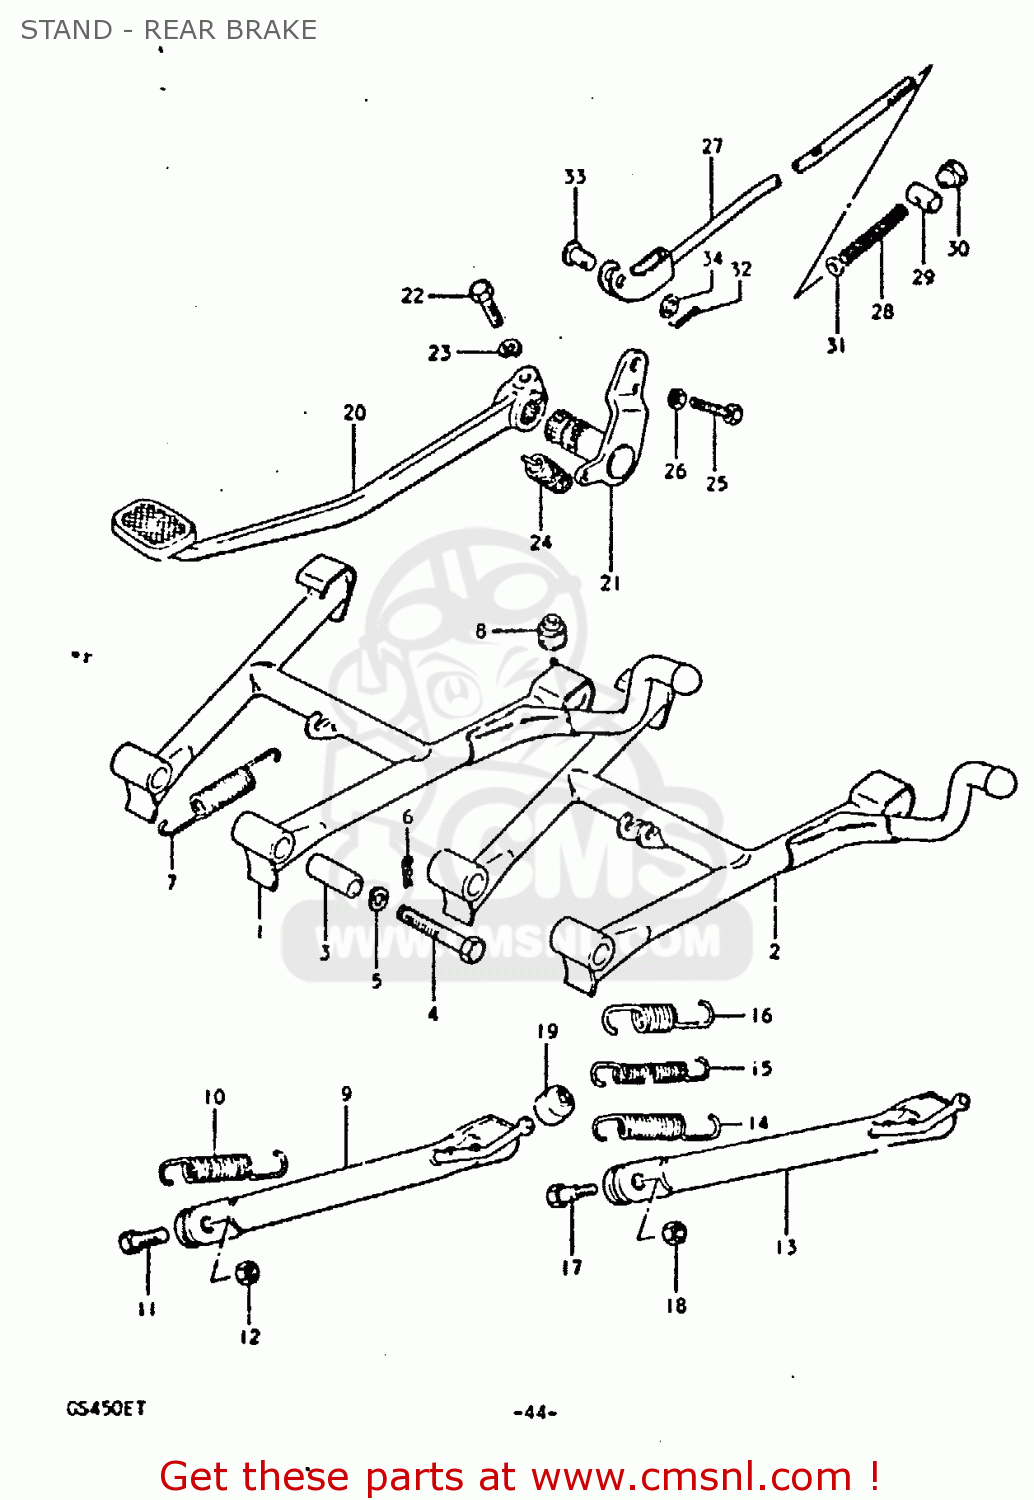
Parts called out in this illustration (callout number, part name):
1	STAND,CENTER
3	SPACER(10X16X38.8)
4	BOLT
5	LOCK WASHER
6	CLIP
7	SPRING
8	CUSHION
9	STAND,SIDE
10	SPRING
11	BOLT(10X30)
12	NUT
19	CUSHION
20	PEDAL,BRAKE
21	ARM,BRAKE PEDAL ROD
22	BOLT
23	LOCK WASHER
24	SPRING
25	BOLT
26	NUT
27	ROD ASSEMBLY,REAR BRAKE
28	SPRING
29	PIN
30	NUT
31	WASHER
32	PIN 20X20
33	PIN(L:13.5)
34	WASHER
